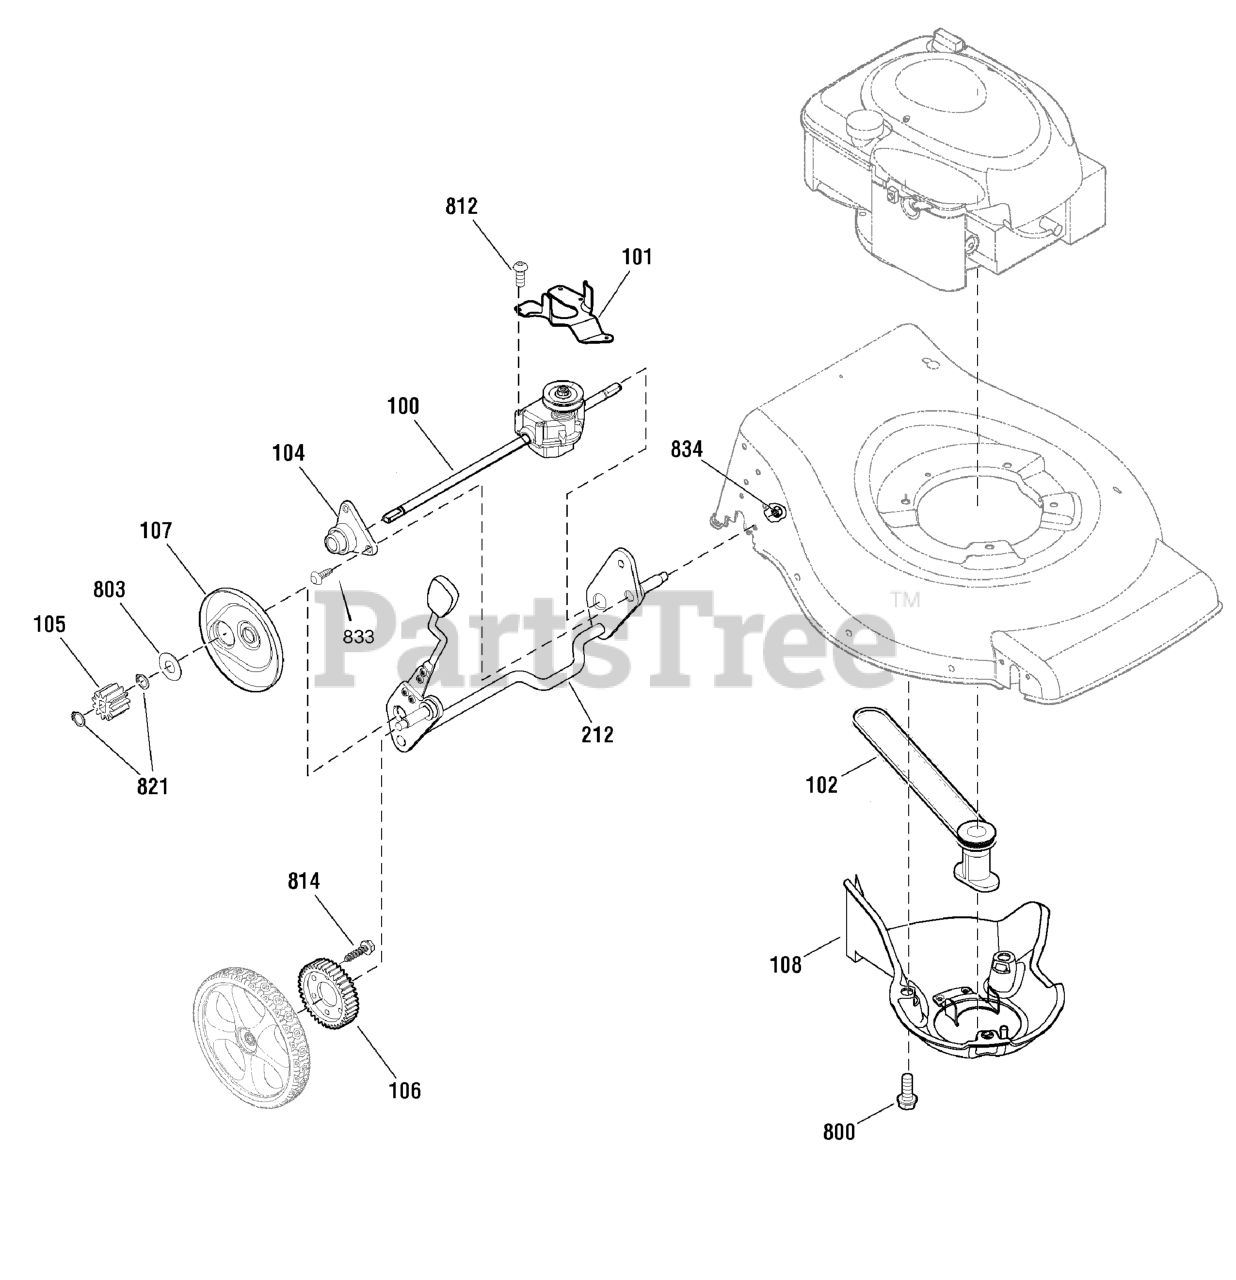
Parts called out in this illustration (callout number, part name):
100	TRANSMISSION
101	BELT GUIDE, Transmission
104	SLEEVE ASSEMBLY, Rear Axle
105	GEAR, Pinion
106	GEAR, Drive
107	DUST COVER
108	BELT COVER ASSEMBLY
800	SCREW, Hex Head, 3/8-16 x 1
803	WASHER, Thrust
812	SCREW, #10 x 1
814	SCREW, 1/4-15 x 3/4
821	RING, External Retaining
833	SCREW, Torx, 1/4-20 x 5/8
834	NUT, Flange Lock, 1/4-20
